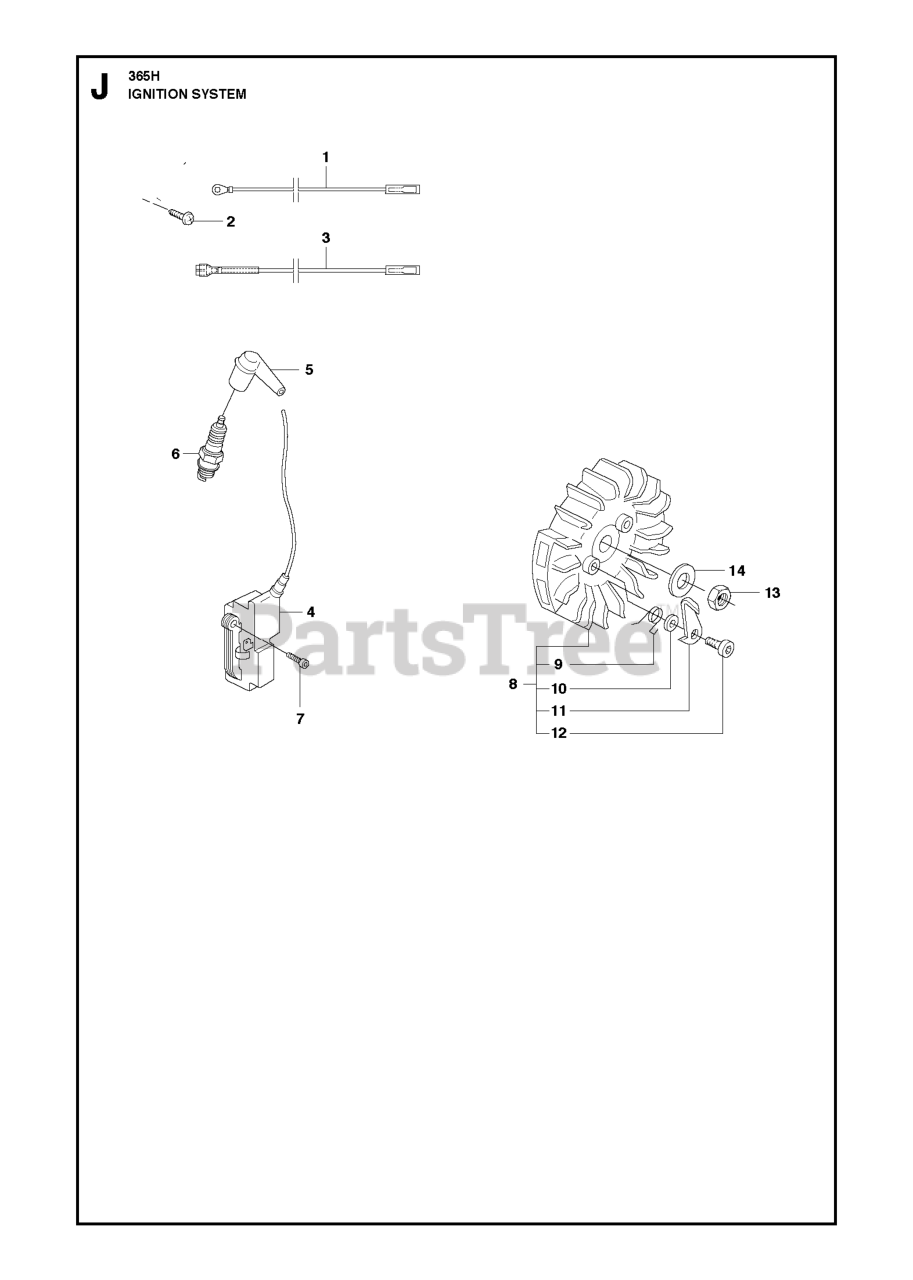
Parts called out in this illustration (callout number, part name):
4	IGNITION MODULE
5	SPARK PLUG CONN. KIT
6	SPARK PLUG M14X1.25 NGK BPMR7A
7	SCREW IHSCM M5X20 12.9 TBO SE
12	SCREW M5X14
14	WASHER 8.4X16
